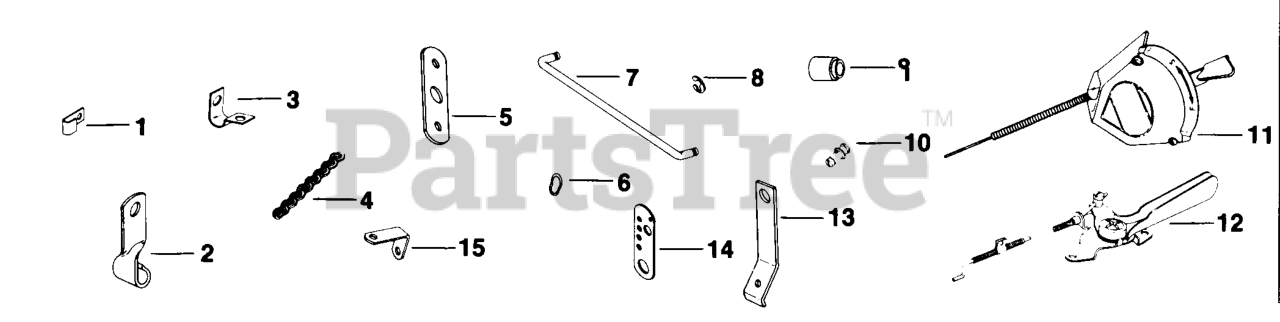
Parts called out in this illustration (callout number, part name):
5	LEVER, BELLCRANK
6	WASHER, SPRING 11/32"
8	RETAINER
10	Kit, clamp
14	BRACKET-DISCONTINUED
15	BRACKET, ADJUSTING SCREW - DISCONTINUED
